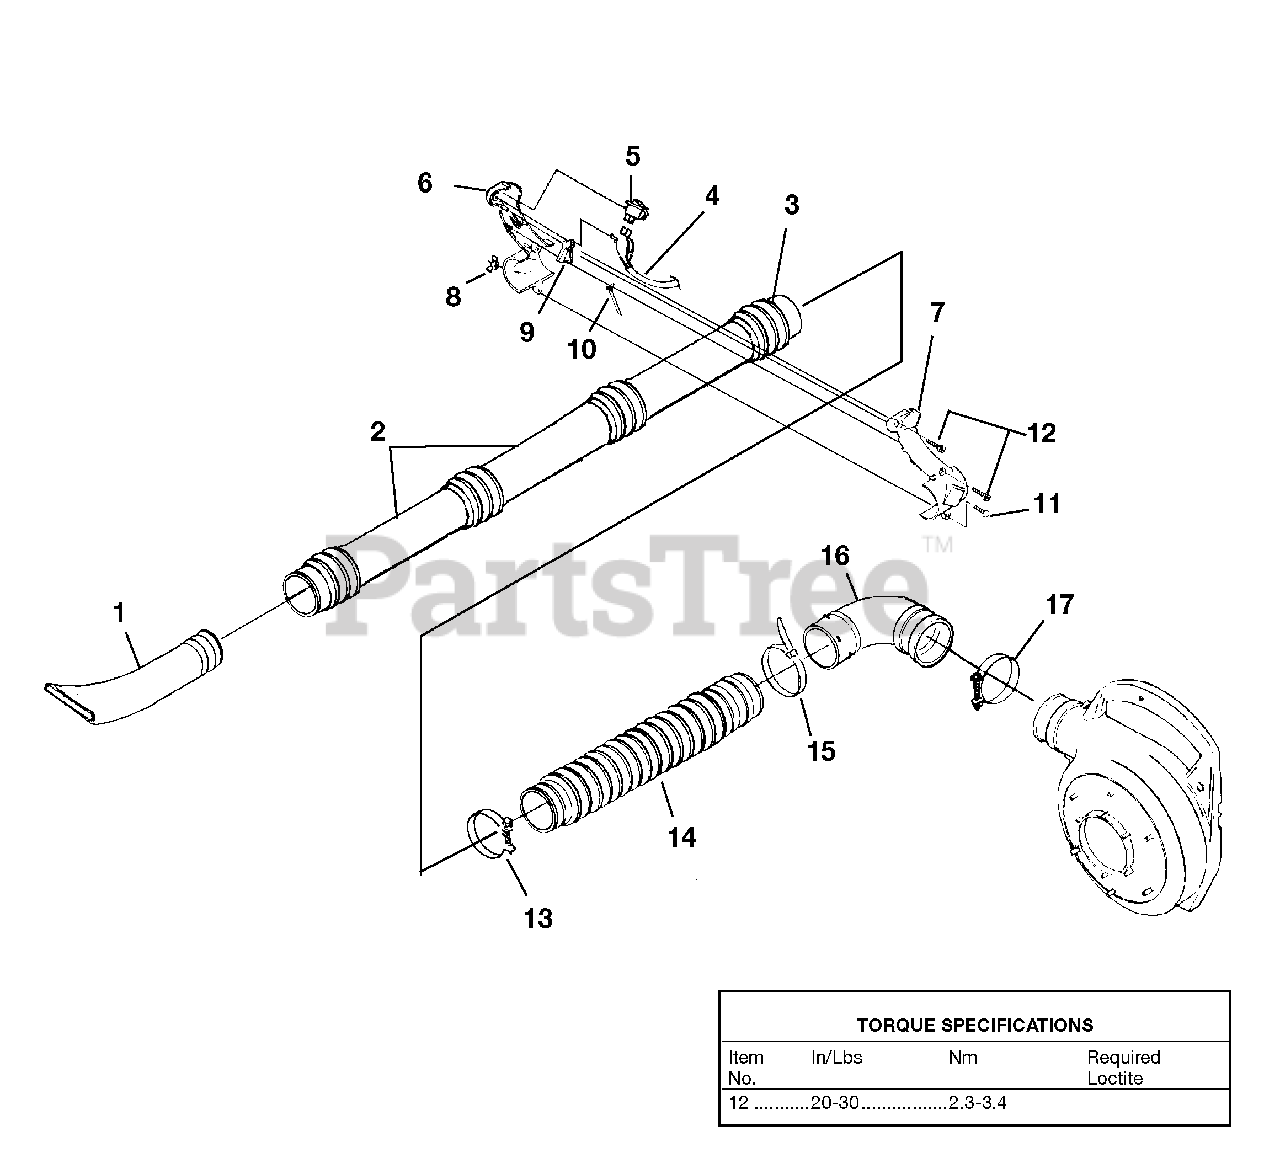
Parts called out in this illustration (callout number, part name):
1	SWEEPER NOZZLE
2	LOWER TUBE
3	UPPER TUBE
4	CABLE-Throttle w/ Ignition Leads
6	HANDLE-Control (Right)
7	HANDLE-Control (Left)
8	NUT - Wing (10-24)
9	TRIGGER
10	LATCH-Trigger
11	BOLT-Rib Neck, Rnd. Hd. (10-24 X 7/8")
12	SCREW-Thread Form. (10-14 X 3/4")
13	CLAMP (#87)
14	BELLOWS-Plastic
15	CABLE-Tie
16	ELBOW-Curved
